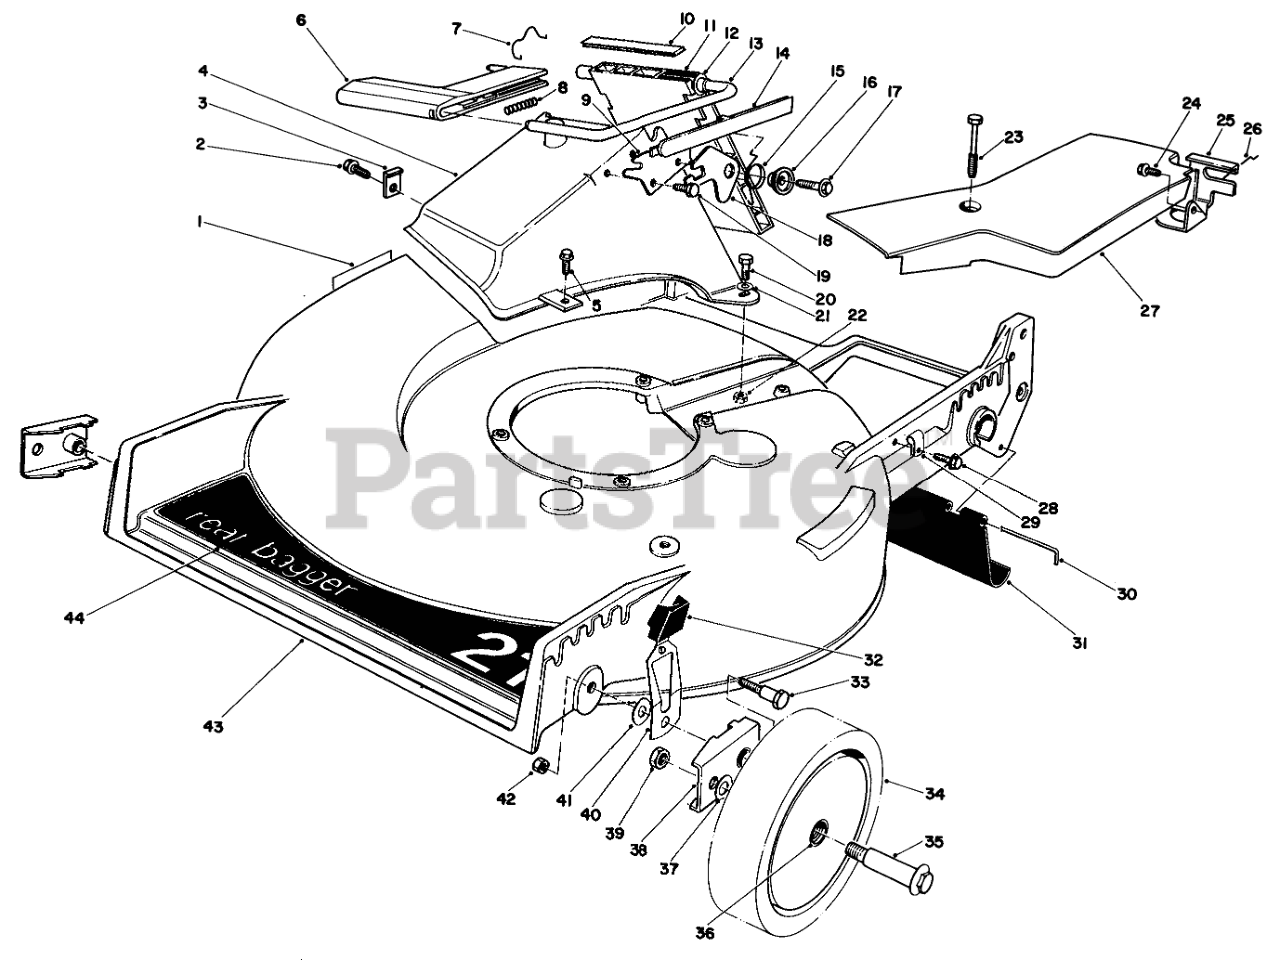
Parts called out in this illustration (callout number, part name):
1	DECAL-DANGER
2	SCREW
3	TUNNEL CLIP
4	Tunnel Discharge
5	Screw
6	Handle-Door
7	DOOR RET SPRING
8	Spring
9	DOOR LATCH PLATE
10	DOOR COVER
11	Door Discharge
12	BUSHING-NYLON
13	DOOR ROD +
14	DOOR HANDLE COVER
15	TORSION SPRING
16	DOOR SPACER
17	SCREW-HWH
18	SAFETY LATCH
19	SCREW-PLASTITE
20	SCREW-HH
21	WASHER-FLAT
22	NUT-LOCK, NI
23	SCREW-HHFTF
24	SCREW-HWHTF
25	Bracket-Traction Adj.
26	RETAINER-CABLE
27	Cover-Belt
28	SCREW
29	CLAMP-CABLE
30	ROD-SHIELD
31	SHIELD-TRAILING
32	KNOB-ARM
33	PIVOT SCREW
34	Wheel & Tire Assembly
35	BOLT-WHEEL
36	BUSHING
37	WASHER
38	HP PIVOT ARM ASM
39	NUT-LOCK, NI
40	Spring Arm
41	WASHER-PIVOT
42	Nut
43	21 SP RB HSG/DECAL
44	DECK DECAL
